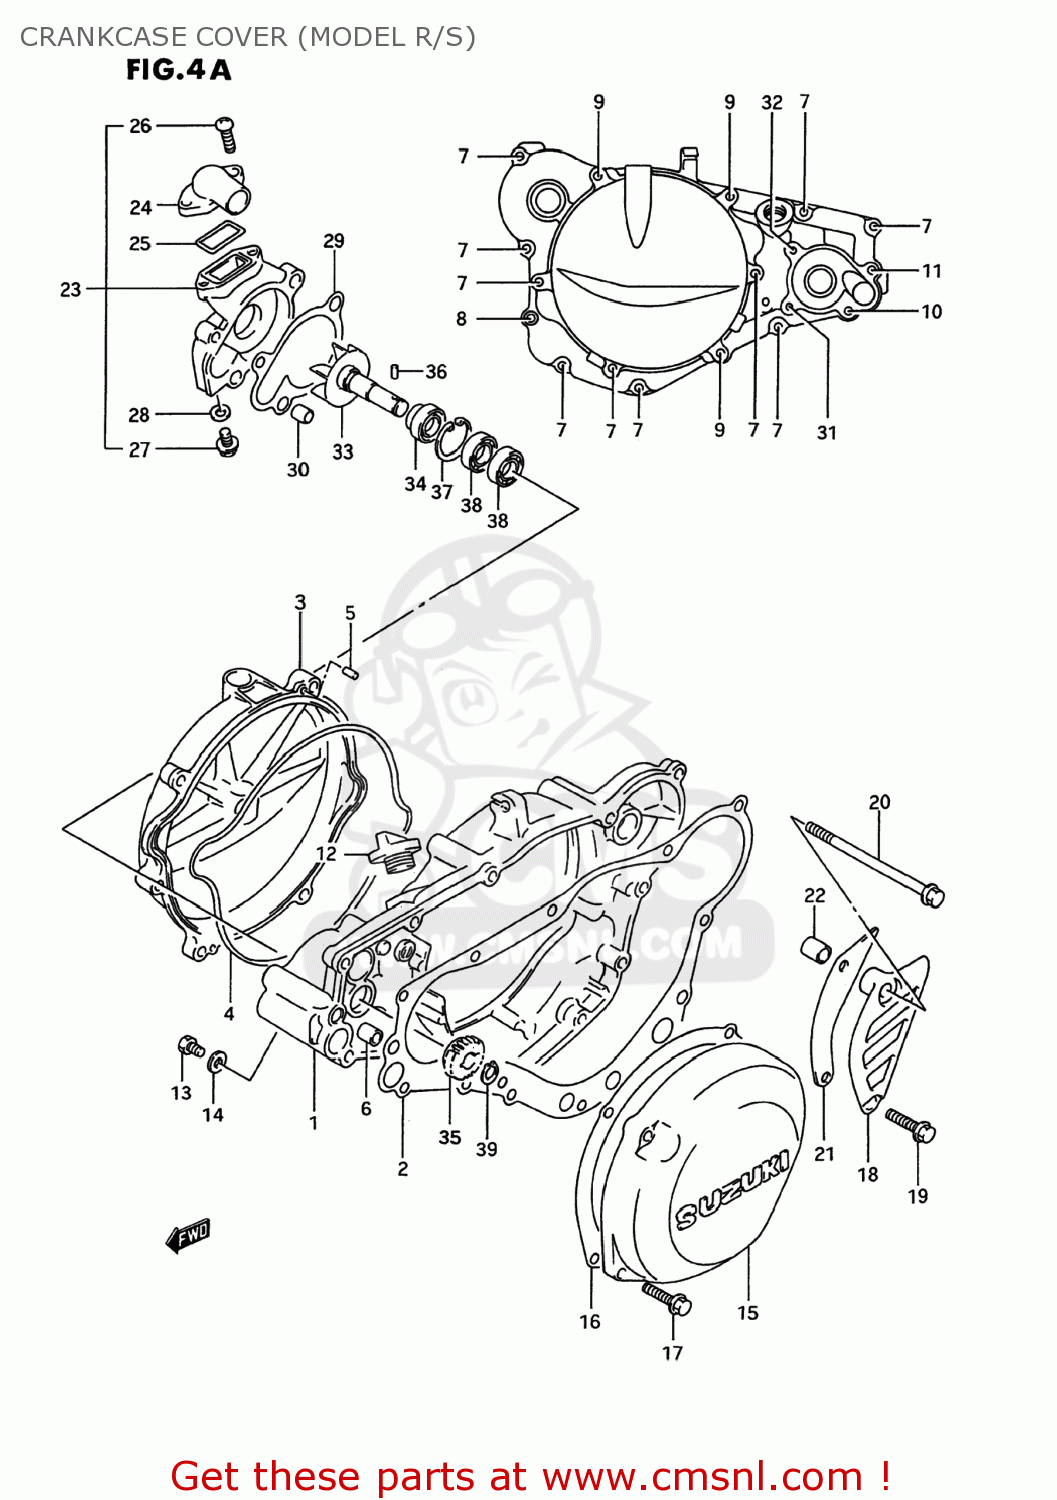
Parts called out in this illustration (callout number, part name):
1	COVER SET,CLUTCH
2	GASKET,CL COVER
3	COVER,CLUTCH OUTER
4	O RING,CLUTCH COVER OUTER
5	PIN
6	PIN
7	SCREW
8	BOLT
9	BOLT
10	BOLT
11	BOLT
12	PLUG SET
13	SCREW(6X10)
14	GASKET(6.2X11X1).2 (NAS)
15	COVER,MAGNETO
16	GASKET,MAGNETO COVER
17	SCREW
18	COVER,ENGINE SPROCKET
19	SCREW
20	BOLT
21	PLATE,FR CHAIN GUIDE(13T)
22	SPACER(6.5X10.5X25)
23	CASE ASSY,WATER PUMP
24	CONNECTOR
25	O RING,WATER PUMP CONNECTOR
26	SCREW
27	BOLT
28	WASHER
29	GASKET,WATER PUMP CASE (NAS)
30	PIN
31	SCREW
32	BOLT,G/S SWITC
33	IMPELLER,WATER PUMP
34	SEAL,WATER PUMP OIL
35	GEAR,WATER PUMP DRIVEN
36	PIN(3X13.8)
37	CIRCLIP
38	BEARING
39	CIRCLIP,10MM
